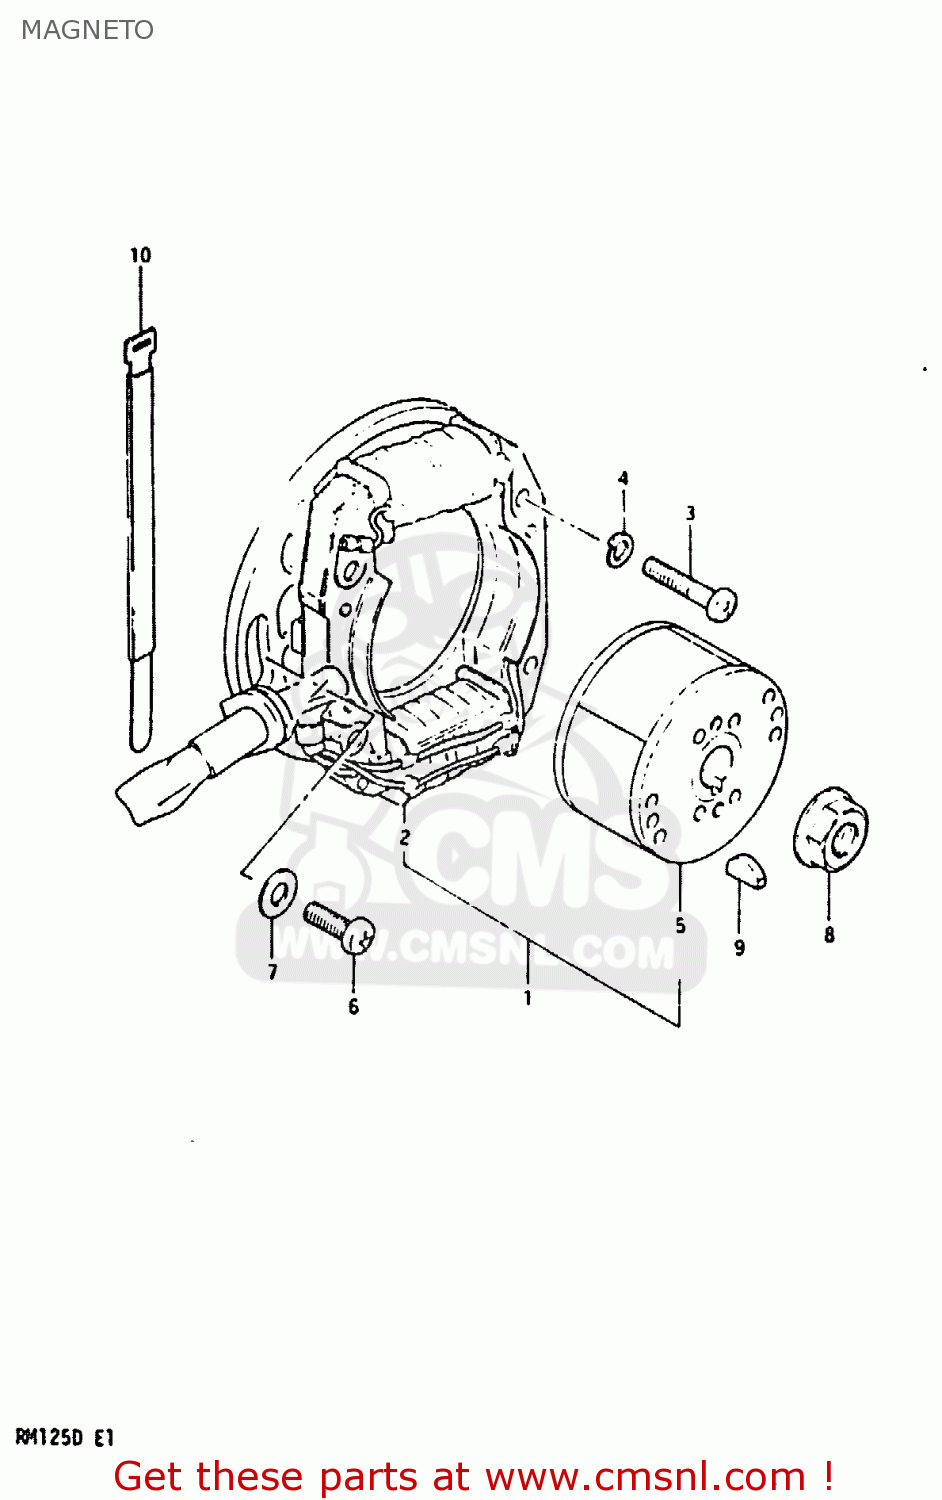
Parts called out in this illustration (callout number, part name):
1	MAGNETO ASSEMBLY
2	STARTER ASSY
3	SCREW 5X20
4	LOCK WASHER
5	ROTOR ASSEMBLY
6	SCREW
7	WASHER
8	NUT
9	KEY 4MM
10	CLAMP
